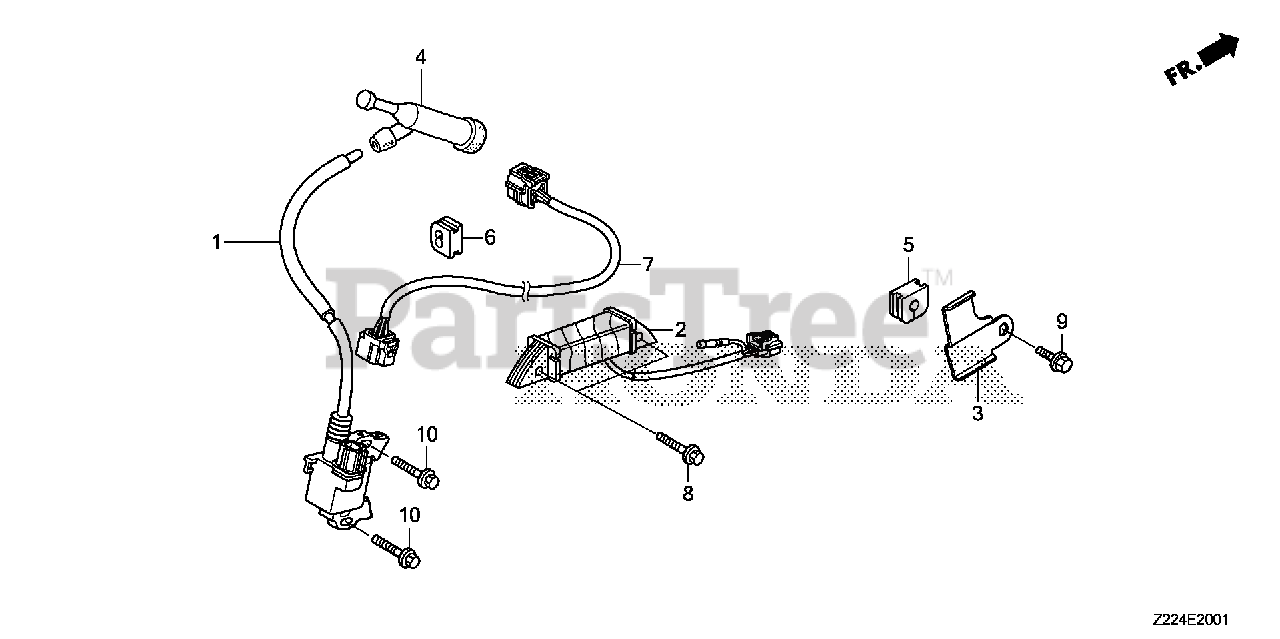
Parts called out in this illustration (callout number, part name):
1	COIL ASSY., IGNITION
2	COIL ASSY., POWER
3	BRACKET B, HARNESS
4	CAP ASSY., NOISE SUPPRESSOR (NGK Y-EZD)
5	GROMMET, WIRE
6	GROMMET, WIRE
7	WIRE HARNESS ASSY., ENGINE
8	BOLT, FLANGE (6X28) (CT200)
9	BOLT, FLANGE (6X12) (CT200)
10	BOLT, FLANGE (6X28) (CT200)
